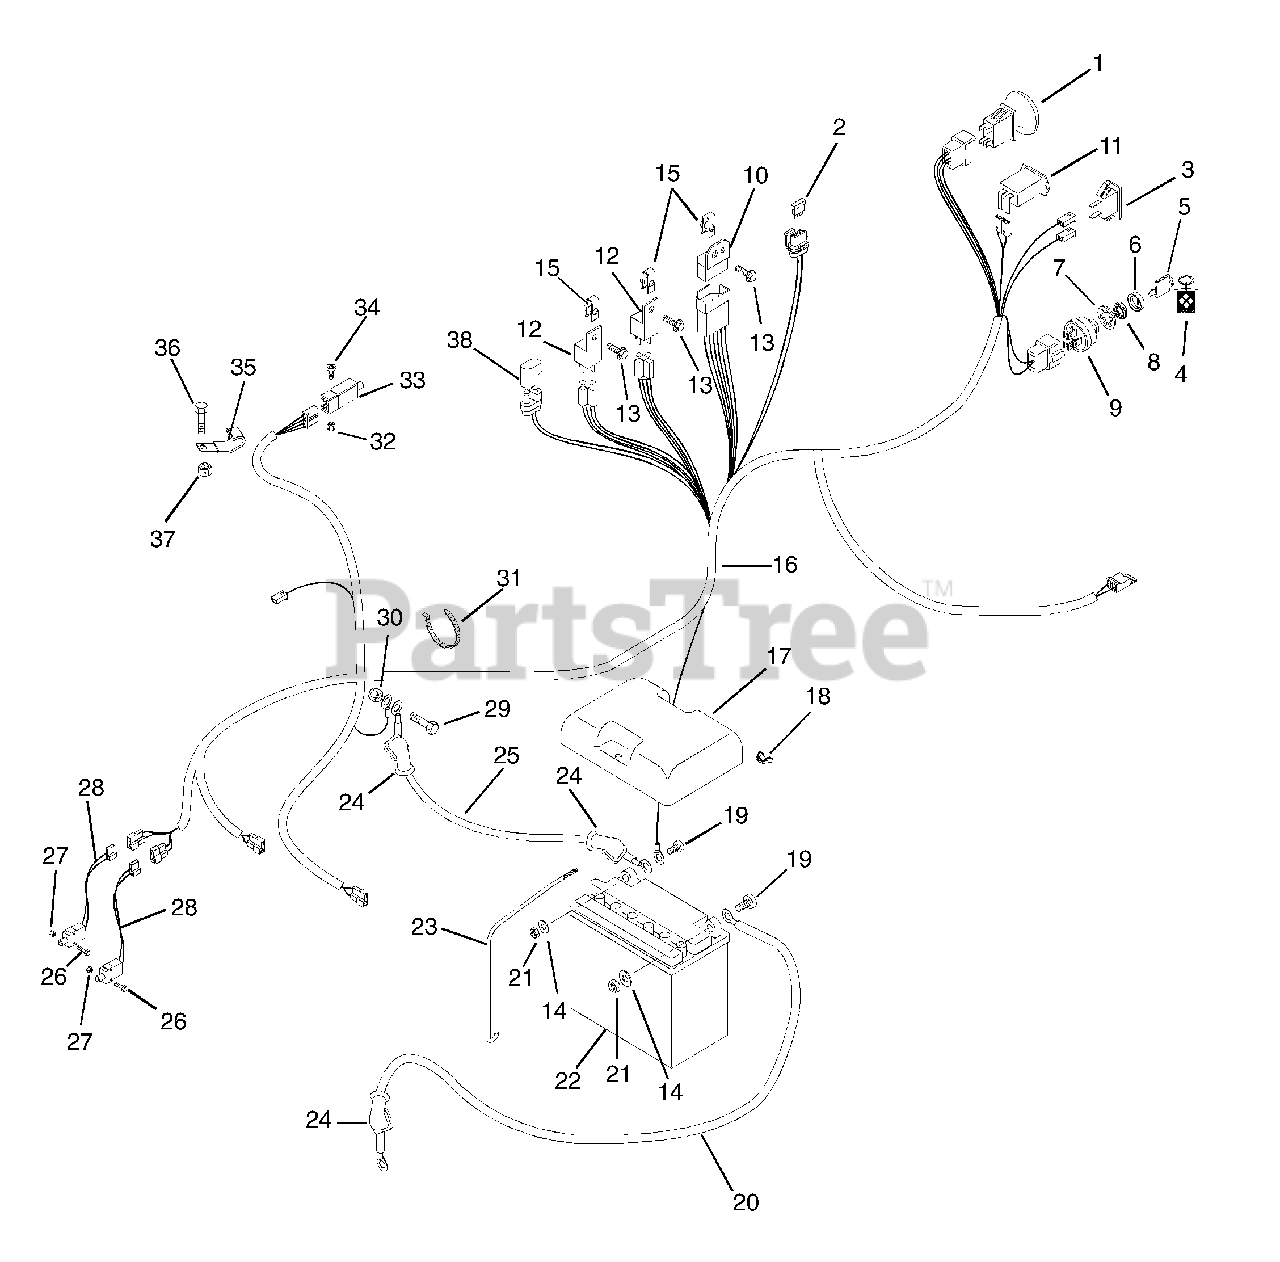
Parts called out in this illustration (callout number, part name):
1	Switch-Clutch with Retainer Ring
2	Fuse, 30 Amp
3	Light-Indicator
4	Key Chain
5	Ignition Switch Key
6	Cap-Ignition Switch
7	Nut-Panel .562-24
8	Washer-Lock-Internal .563 x .040
9	Key Switch
10	Module, Time Delay
11	Hour Meter
12	Relay
13	Screw-Machine 10-24 x .75 Hex Washer Head
14	Washer-Flat-Steel .281 x .620 x .065
15	Retainer Nut 10-24
16	Harness-Wiring
17	Cover-Battery
18	Nut-Locking-Wing .250-20
19	Bolt-Hex .25-20 x .75 Grade 5
20	Cable-Starter
21	Nut-Hex .25-20
23	Rod-Battery
24	Boot-Insulator
25	Cable-Negative Battery
26	Screw-Machine 6-32 x .75
27	Nut-Locking-Nylon 6-32 w/Insert
28	Switch
29	Bolt-Hex .31-18 x 1.00 Grade 5
30	Nut-Locking-Center .31-18
31	Tie-Wrap-Black
32	Nut-Locking-Nylon 10-24 w/Insert
33	Switch-Single Pole N.O.
34	Screw-Machine .38-7.0
36	Bolt-Hex .38-16 x 1.00 Grade 5
37	Nut-Locking-Center .38-16
38	Molded Diode Plug
